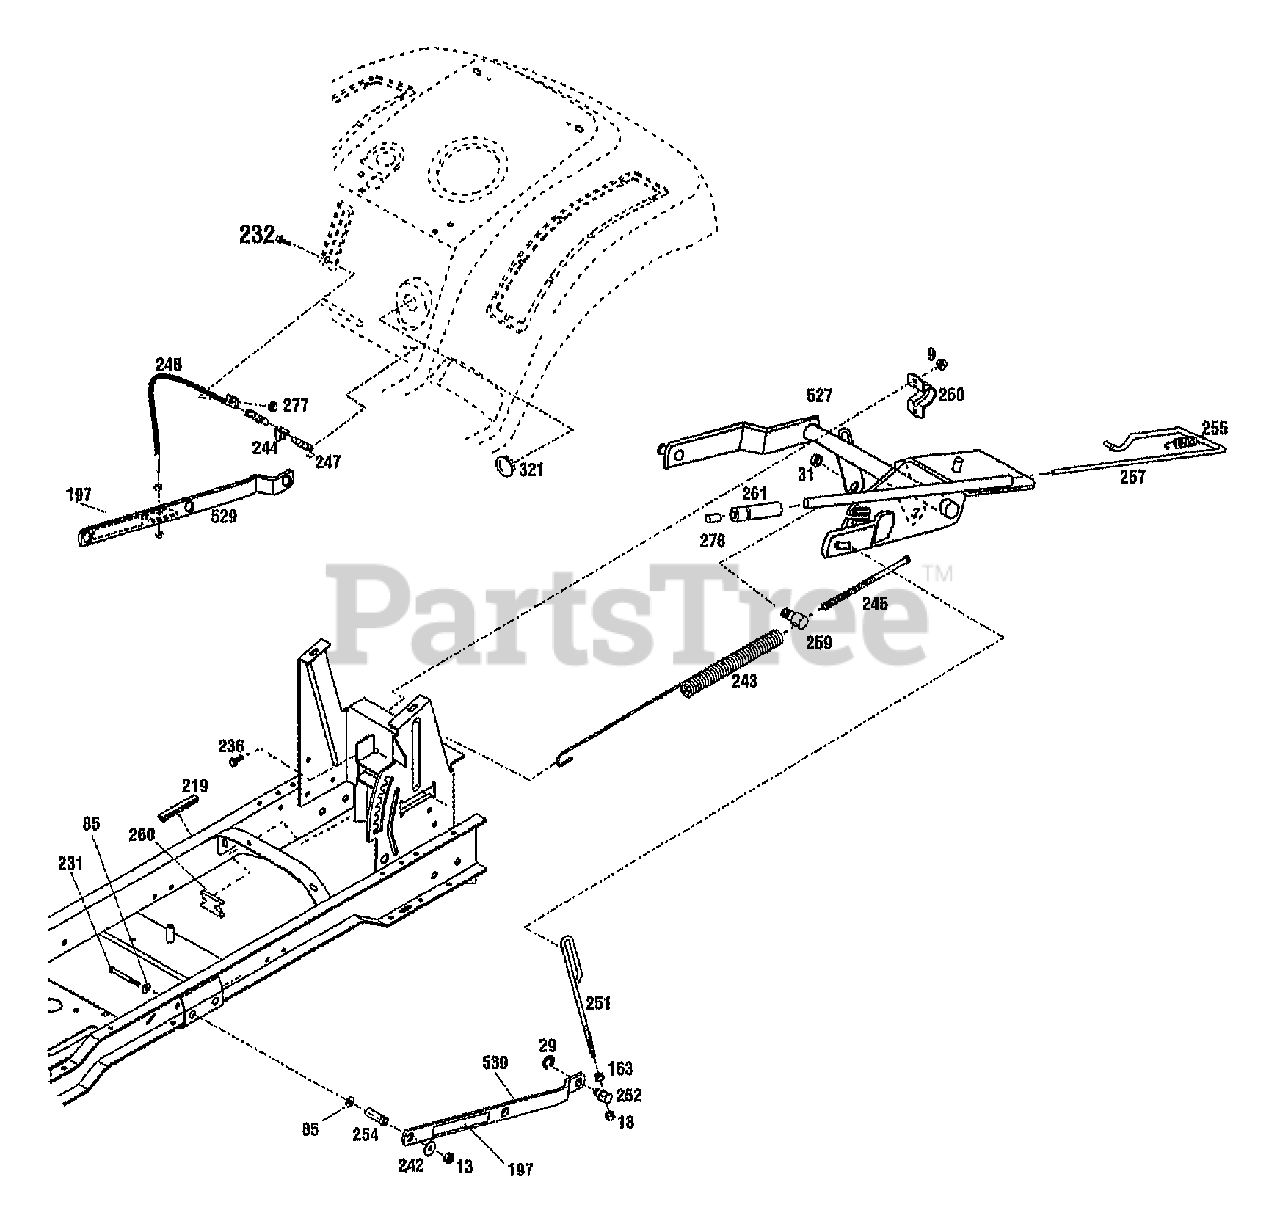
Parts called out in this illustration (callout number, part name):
9	NUT-HFLK 5/16-18 ZP
13	NUT-LOCK 3/8-16
29	RING-RETAINING
31	NUT-H/LK 5/8-11
85	WASHER-FLAT 3/8 SAE
163	NUT-HEX 3/8-16 ZP
197	DECAL-WARNING
231	SCR-HH 3/8-16X3.0 G5 ZP
232	SCR 10-24 X 5/8
236	SCR-HFLK 5/16-18X.75 ZP
242	WASHER-1.5X.375X.18 ZP
243	SPRING-LIFT ASSIST
244	INDICATOR-HEIGHT
245	SCR-HH 3/8-16X5
247	SPRING-EXTENSION
248	ASSM-CABLE
250	CLAMP-LIFT
251	ROD-LIFT
252	SWIVEL-REAR LIFT
254	SPACER
255	SPRING-EXTENSION
259	BLOCK-PIVOT
260	SPRING-ANCHOR
261	GRIP-LIFT
276	BUTTON-LIFT
321	PLUG-DOME
529	ASSM-RT LIFT LINK
530	ASSM-LT LIFT LINK
